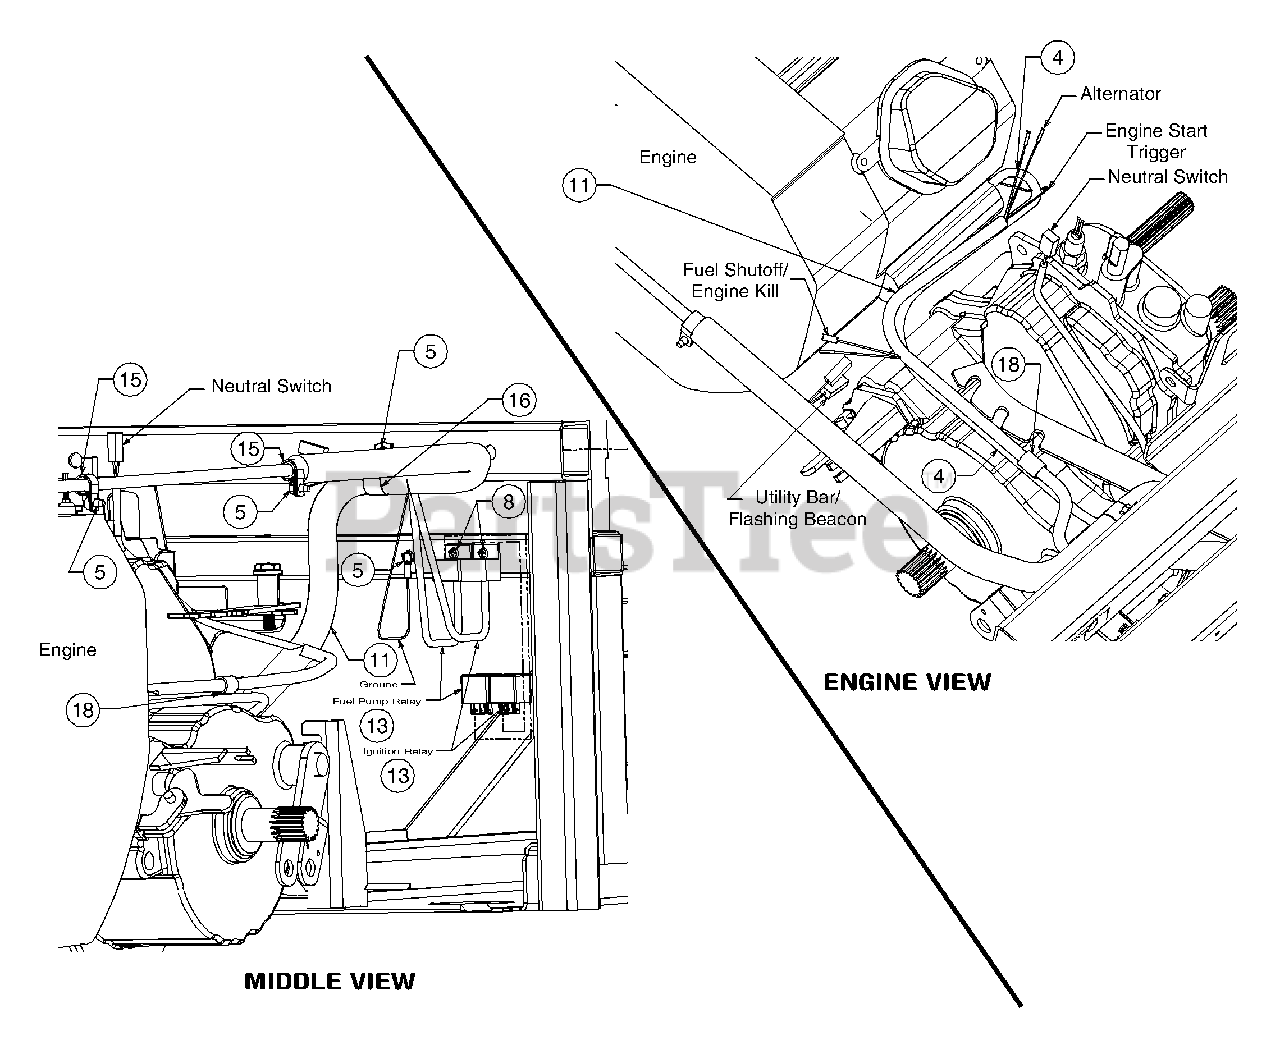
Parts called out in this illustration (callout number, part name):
4	Harness Assembly, Positive
5	Screw, Self-tapping, 1/4-20 x 0.500
8	Screw, #10-24 x 0.75
11	Harness, Utility Wire
13	Relay, 12V 40A
15	Clamp, #10
16	Clamp, #14
18	Heat Shield Cable Clip
